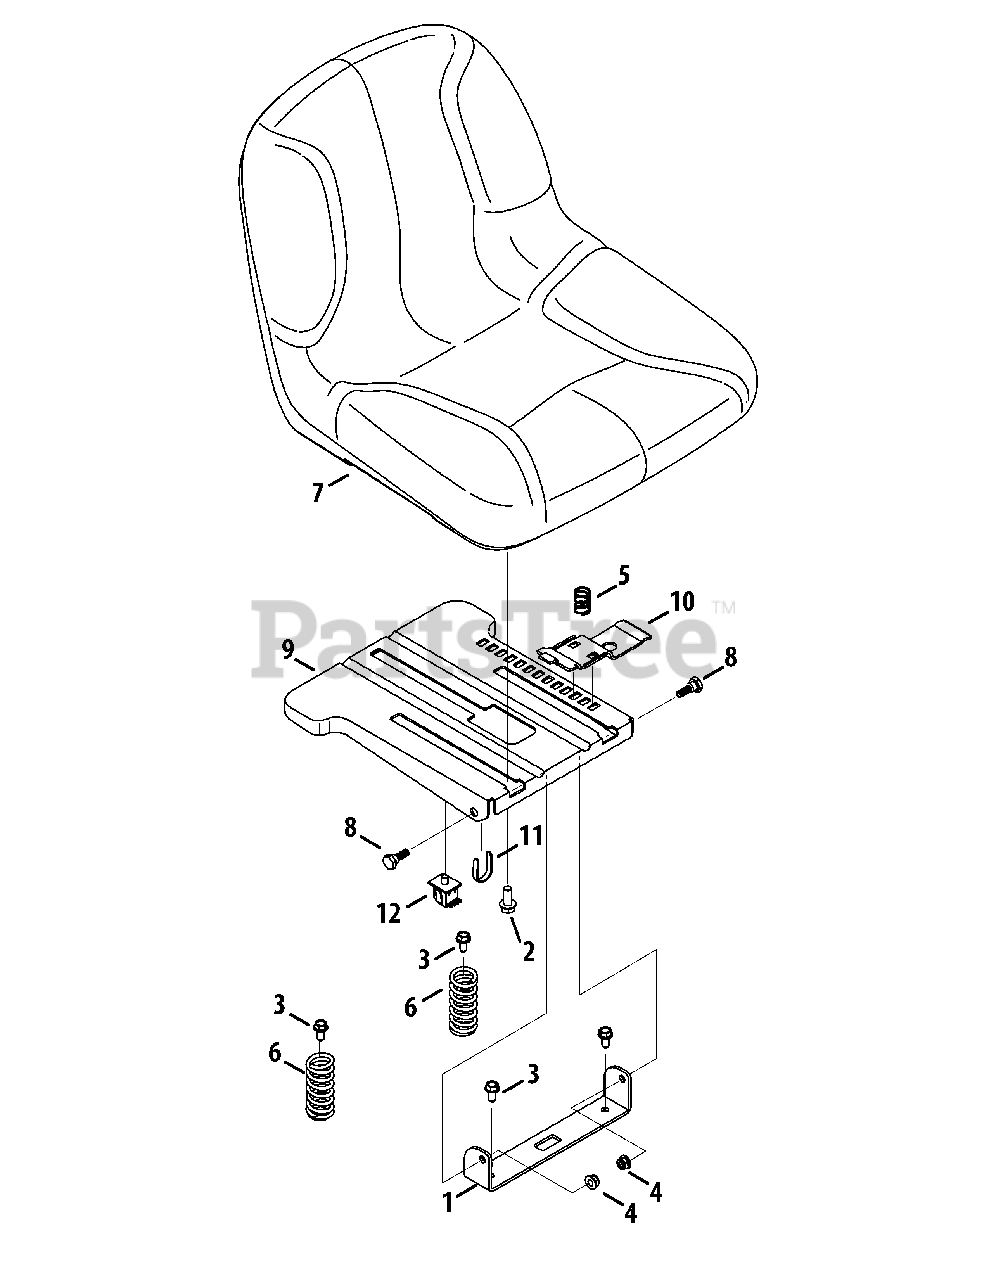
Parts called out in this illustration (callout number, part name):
1	Seat Bracket
2	Hex Flange Bolt, 3/8-16 x .875
3	Hex Washer Screw, 5/16-18 x .750
4	Flange Lock Nut, 5/16-18
5	Compression Spring, .68 x 1.065 x .055
6	Compression Spring, 1.50 x 3.90 x .200
8	Shoulder Screw, 5/16-18 x .437 x .268
9	Seat Mount Bracket
10	Seat Adjustment Lever
12	Seat Switch
